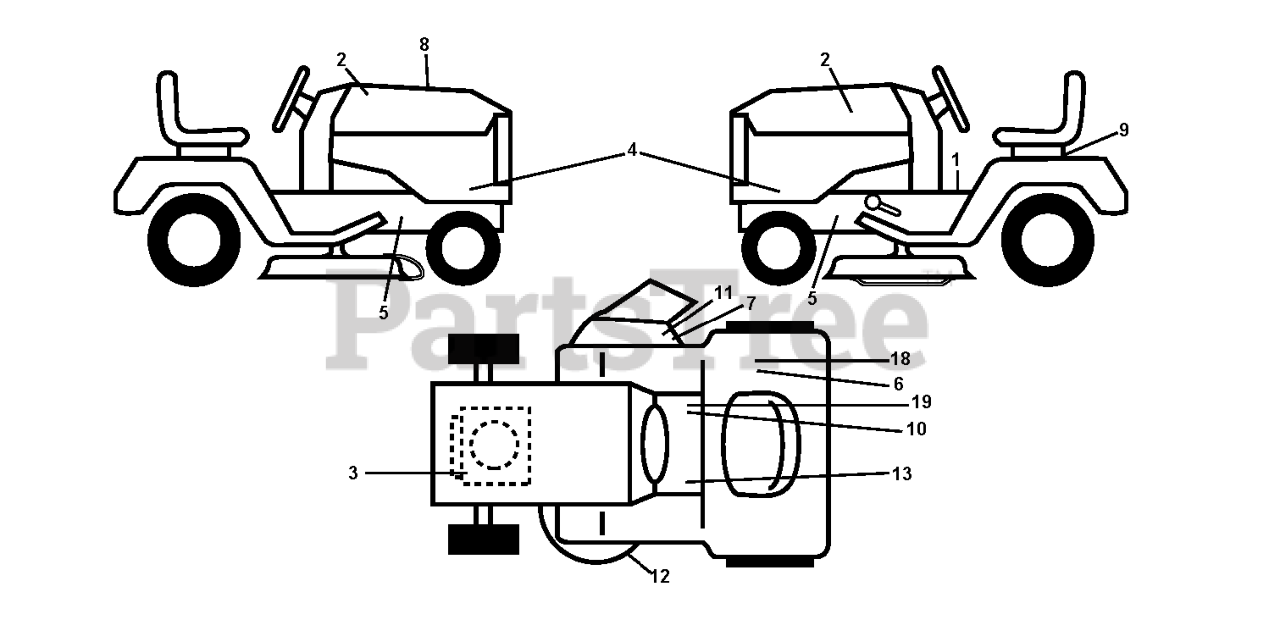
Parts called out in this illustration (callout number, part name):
1	LABEL
2	RP.DECAL.BADGE.170MM.TEXTLOGO
3	DECAL
6	DECAL 80 DBA
7	DECAL, DEFLECT WARNING
9	DECAL BTRY SYMBOLS
10	DECAL PARK BRAKE
11	DECAL.INTERNATIONL.CUTFINGER
12	DECAL.V-BELT.SCHEMATIC.36/38/9
13	DECAL
18	DECAL
19	DECAL
